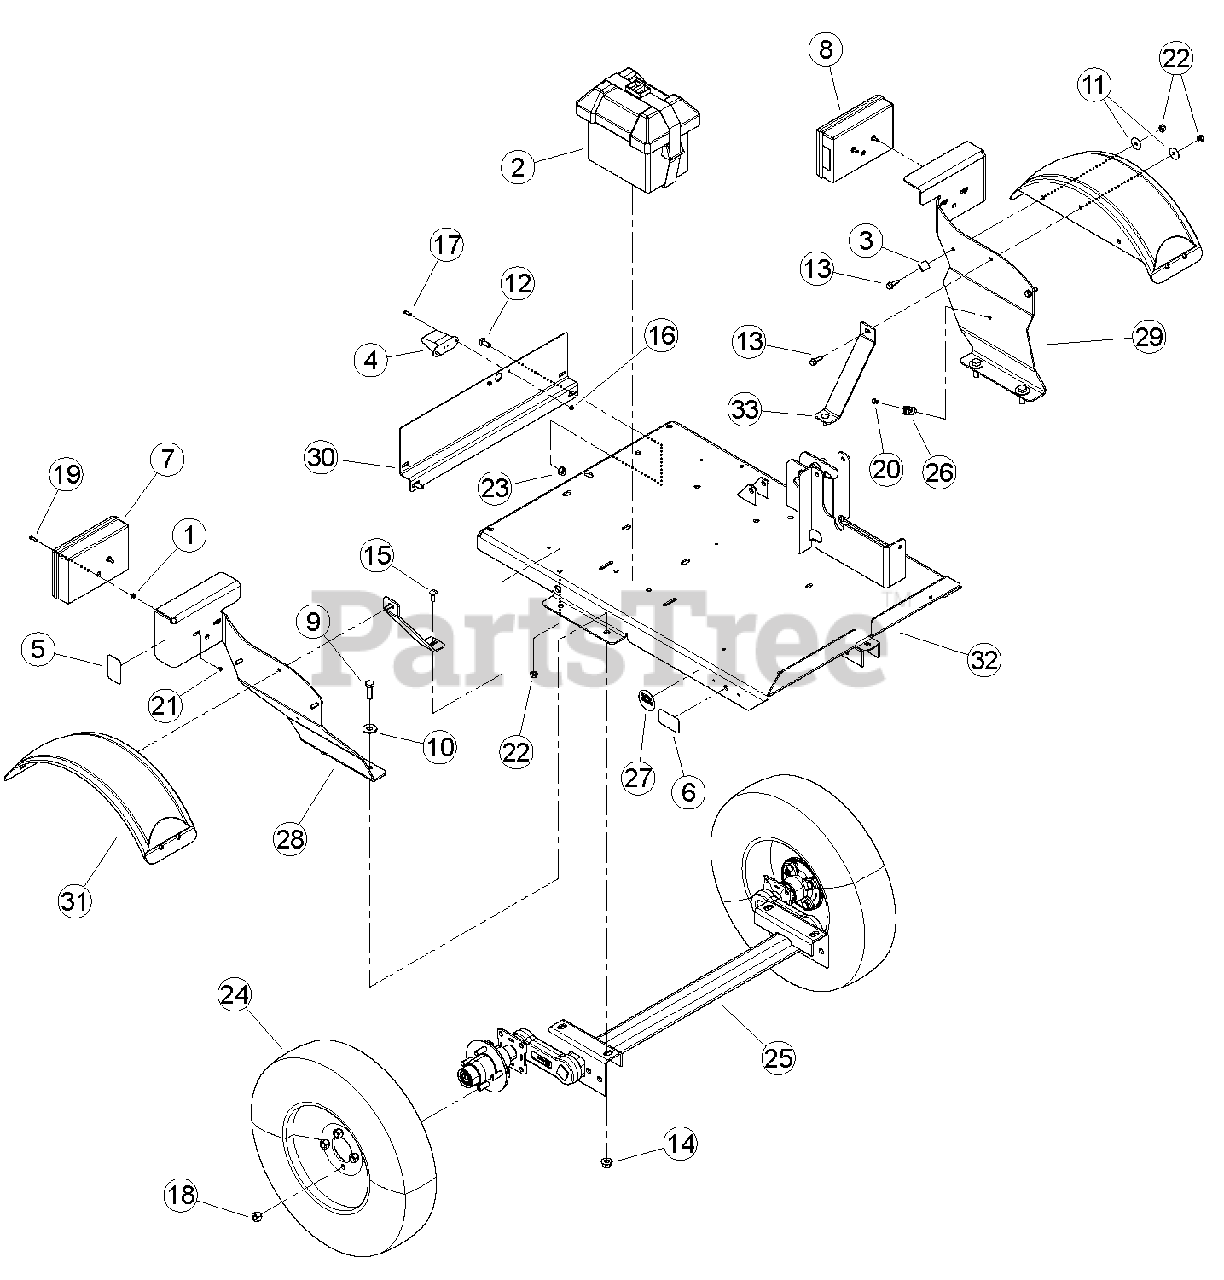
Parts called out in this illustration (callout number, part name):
1	GROMMET, 1/4 X 5/8 RUBBER
2	BOX, SMALL BATTERY
3	CLAMP, 9/16 COATED
4	LIGHT, LICENSE PLATE
5	REFLECTOR, WIDE ANGLE RED
6	REFLECTOR, WIDE ANGLE AMBER
7	LIGHT, TAIL RH
8	LIGHT, TAIL LH
9	BOLT, 1/2 X 1-1/2 HEX HD GR5 ZP
10	WASHER, 1/2" FLAT ZP-56PCS/LB
11	WASHER, 5/16" FENDER ZP-32PCS/LB
12	BOLT, 3/8 X 1" GR5 CRG NC ZP
13	BOLT, 5/16 X 1 FLANGE NC
14	NUT, 1/2-13 NYLOCK FLANGE
15	BOLT, 5/16 X 1" GR5 CRG ZP
16	NUT, 10/24 NYLOCK TYPE NM ZP
17	SCREW, #10-24 X 3/4" PAN HD PH ZP MCH
18	NUT, 1/2-20 WHEEL
19	BOLT, 10-24 X 3/4" HHCS GR8 PLAIN
20	RIVET, AL BLIND 1/4 X 3/4 DOME HEAD
21	NUT, #10-24 K-LOCK ZP
22	NUT, 5/16-18 NYLOCK FLANGE
23	NUT, 3/8-16 NYLOCK FLANGE
24	ASSEMBLY, 5.30-12 TIRE + SPOKE RIM
25	AXLE, 1000LB TORSION
26	CLAMP, CABLE MOUNT
27	DECAL, NATM COMPLIANCE
28	BRACKET, RH FENDER "CE"
29	BRACKET, LH FENDER "CE"
30	PLATE, MOUNTING
31	FENDER, BLACK PLASTIC DRILLED
32	WELDMENT, CHIPPER TRAILER
33	BRACKET, FENDER
